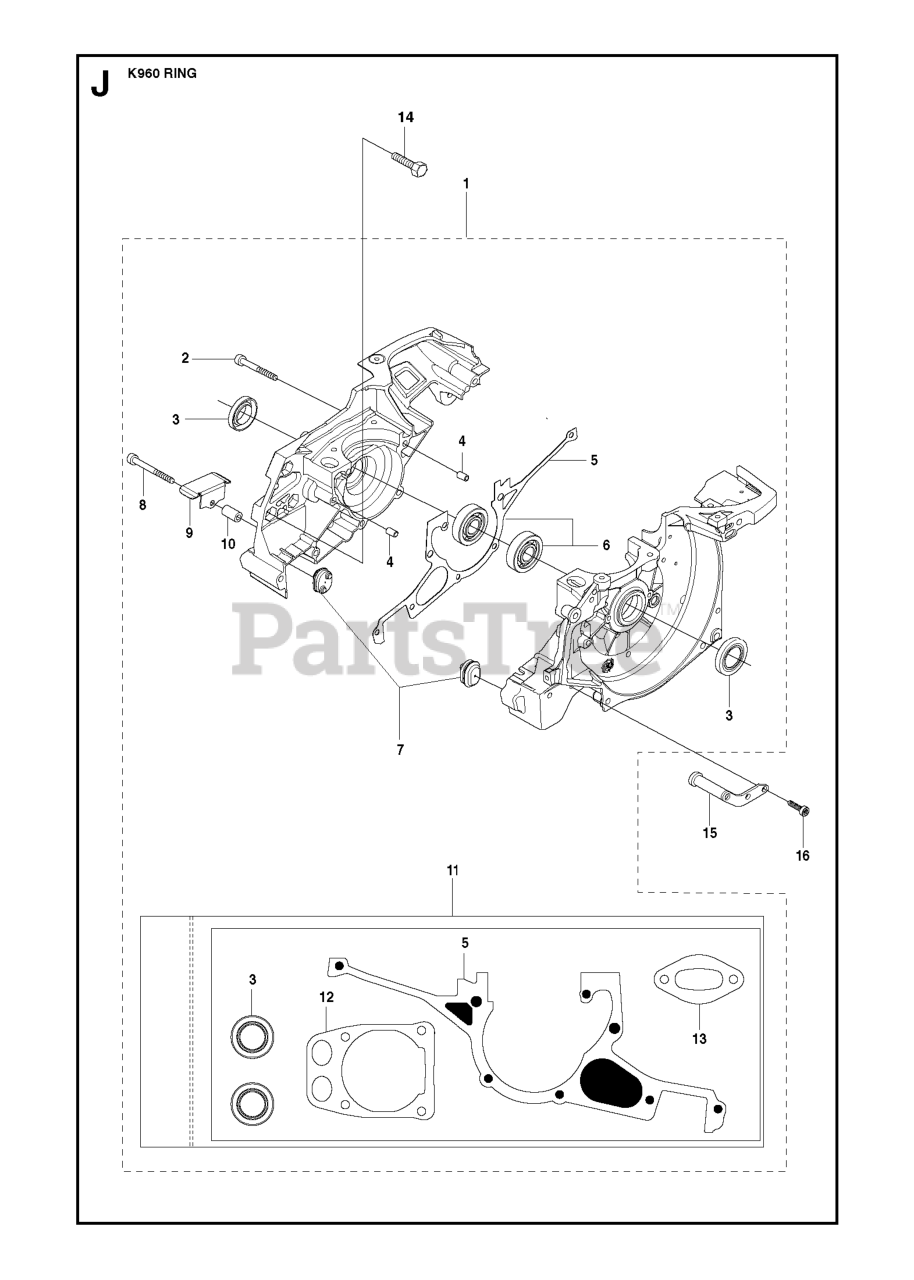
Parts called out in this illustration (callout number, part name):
3	SEALING RING
5	RP GASKET
6	BALL BEARING 6203C3QE6
7	RUBBER BUSHING
9	BELT GUIDE
11	RP GASKET KIT
12	RP GASKET
13	GASKET MUFFLER
